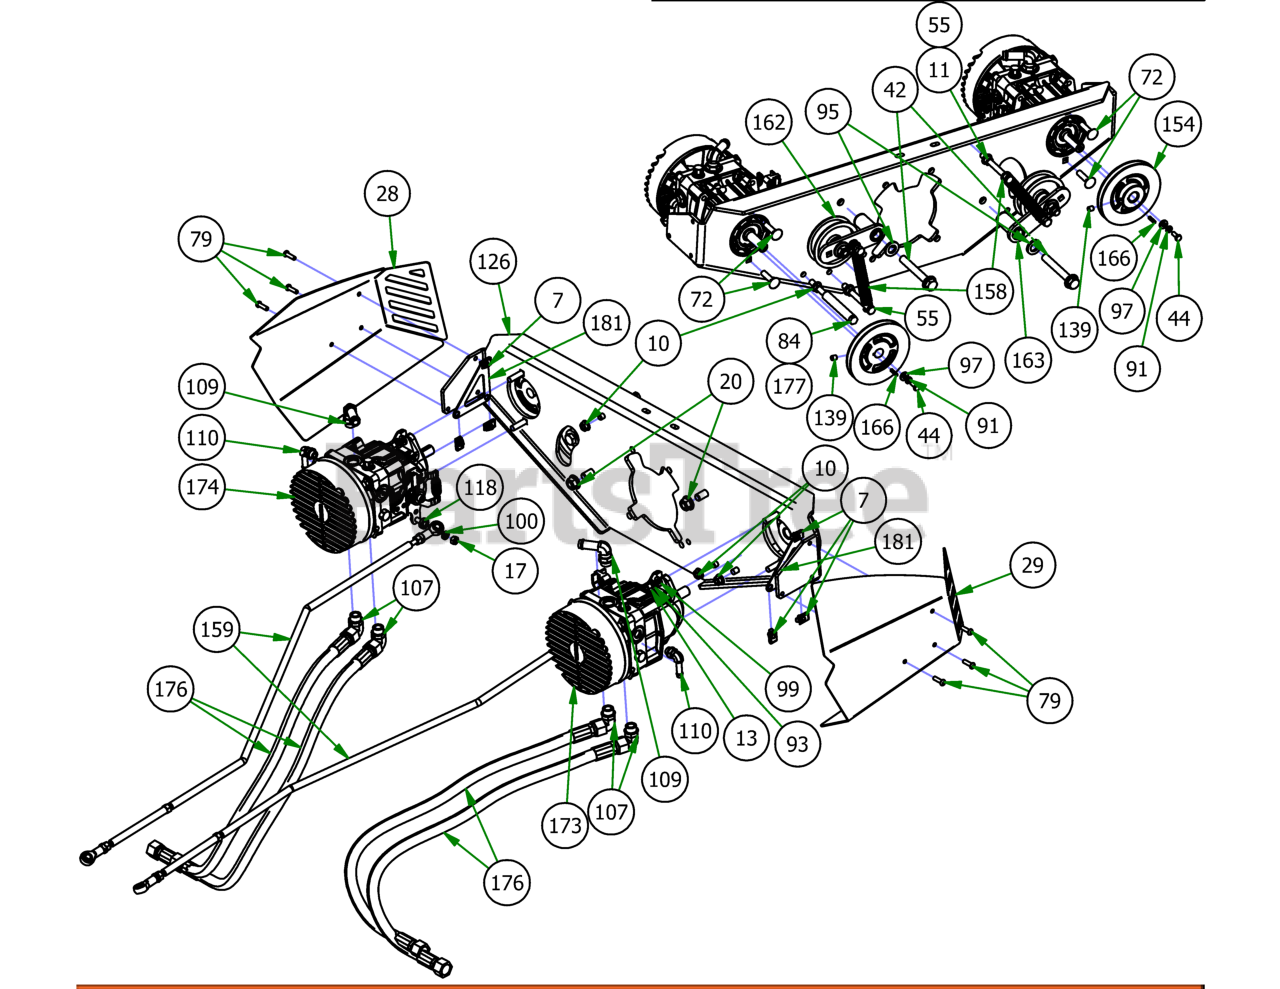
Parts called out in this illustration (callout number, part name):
7	1/4-20 Cage Nut
10	3/8-16 HEX SERRATED FLANGE NUT HARD/ZINC
11	3/8-16 NYLON INSERT FLANGE LOCKNUT (GR.F) ZINC
13	3/8" Hex Nut
20	1/2-13 NYLON INSERT FLANGE LOCKNUT ZINC
28	2019 Horizontal Pump Cover - Right
29	2019 Horizontal Pump Cover - Left
42	1/2-13 X 90MM HEX FLANGE BOLT W/SHOULDER (GR.8) ZINC
44	M6-1.0 X 16MM Hex Bolt
55	3/8-16 X 3-1/2 HEX CAP SCREW (GR.5) ZINC
58	5/16 x 1 1/4 Hex Bolt
72	3/8 x 1 1/2 Carriage Bolt
79	Hexagon Socket Button Head Cap Screw
84	3/8-16 x 5 1/2 Hex Bolt
91	1/4" Lock Washer
93	3/8" Lock Washer
95	.635 ID X 1.120 OD X .140 THICK FLAT WASHER NYLON
97	1/4" Flat Washer
99	5/16" Flat Washer
100	5/16" Lock Washer
107	2019 Outlaw 90 Degree Pump Fitting #6801-10-08
109	90 Degree Fitting, 1/2 x 3/4, 4601-8-8
110	90 Degree Fitting, 3/8 s 9/16
118	ACS Spacer 3/4x3/8x1/4
126	Pump Plate - 2019 Horizontal Gas
139	5/16-24 X 3/8 Set Screw
154	5" Pump Pulley
158	ZT and ACS Handle Spring
159	2019 Renegade Push Rod Assembly
162	2019 Renegade Belt Tensioner LH
163	2019 Renegade Belt Tensioner LH
166	5mm x 1.25" Key
173	2019 Rogue/Renegade Left Pump 16cc
174	2019 Outlaw Renegade Right Pump 16cc
176	2019 Renegade Hydro Hose
177	3/8 hose 4" long
181	Pump Plate Clip Nut Holder
